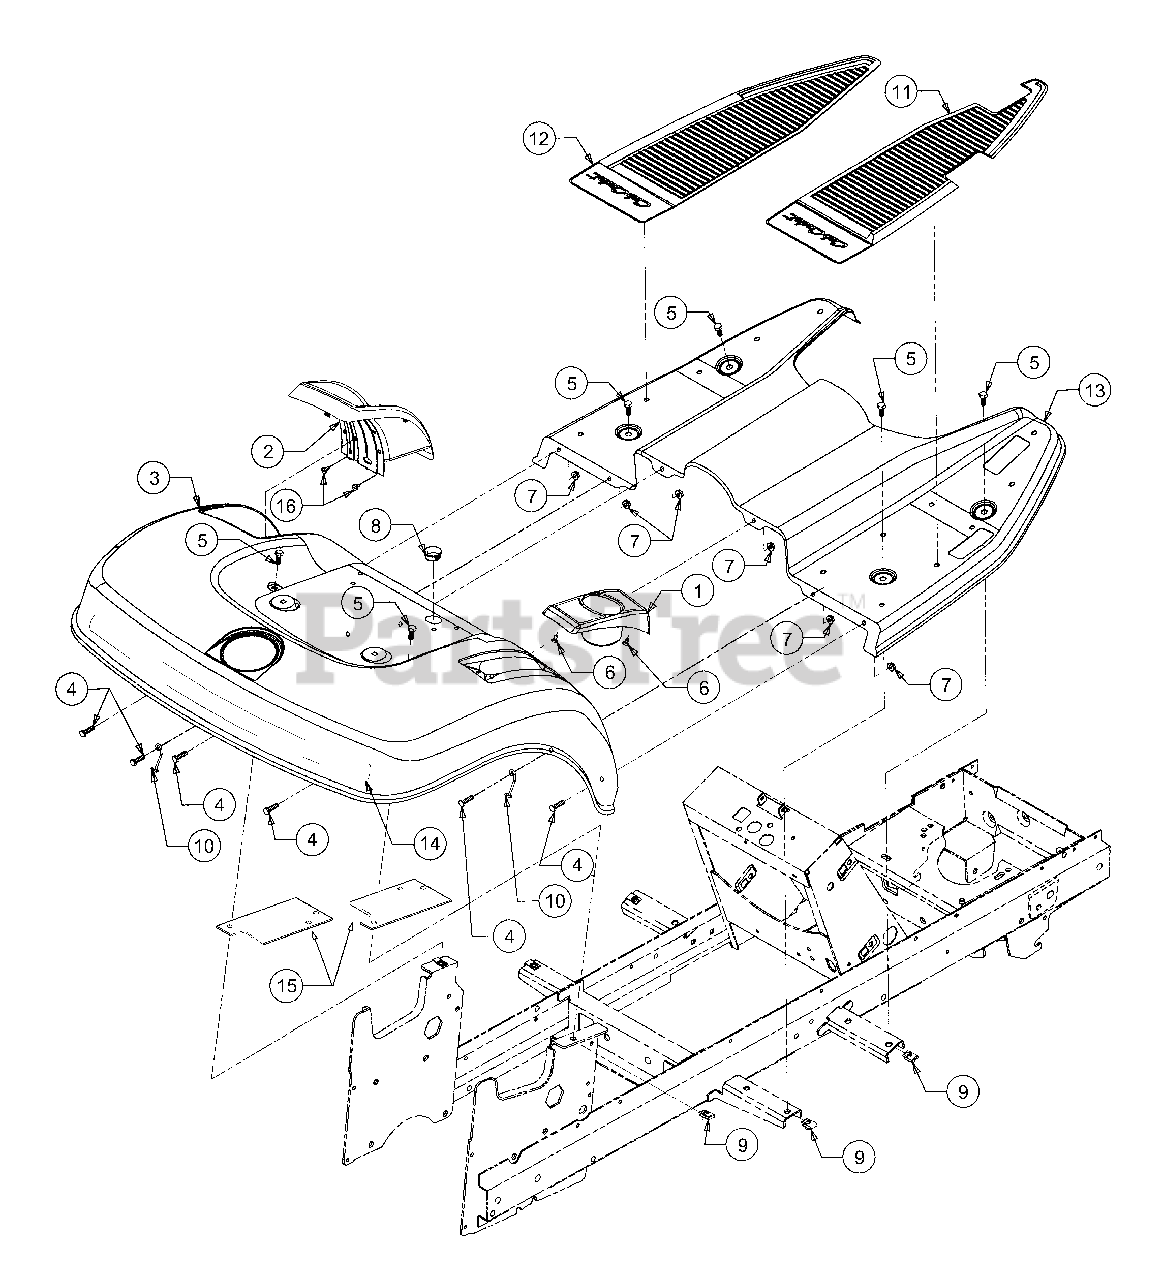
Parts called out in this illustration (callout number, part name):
1	Cup Holder
2	Cover, Implement Lift
4	Screw, Hex Cap, 1/4-20 x .62 GR5
5	Screw, Hex Wash Hd Tapp 5/16-18 x .750
6	Screw, Hex Tapp, #10 x .38 Lg
7	Nut, Hex Flange Lock, 1/4-20
8	Bushing, Snap, 7/8 ID
9	U-Nut, 5/16-18
10	Retainer, Hook
11	Pad, RH Foot
12	Pad, LH Foot
14	Graphic, Rear Fender
